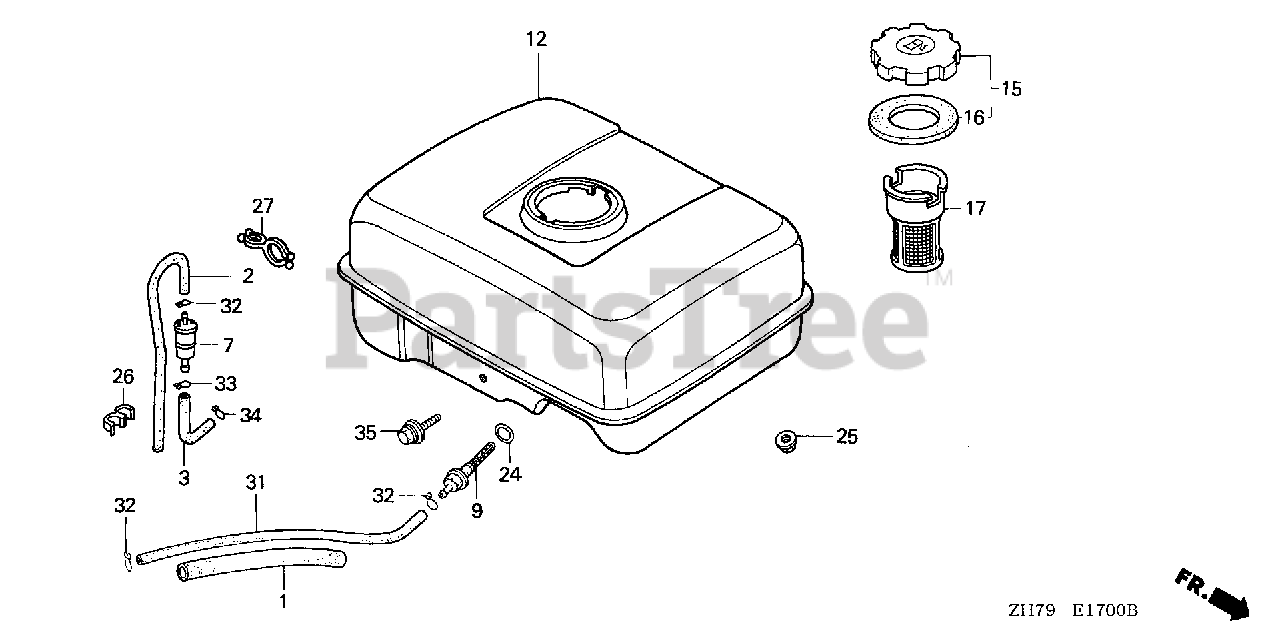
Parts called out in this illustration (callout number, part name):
1	RUBBER, SUPPORTER (107MM)
9	JOINT, FUEL TANK
12	TANK, FUEL *NH31* (MCKINLEY WHITE)
15	CAP, FUEL FILLER
16	GASKET, FUEL FILLER CAP
24	O-RING (13.5X1.5) (ARAI)
25	NUT, FLANGE (6MM)
31	BULK HOSE, FUEL (4.5X3000) (4.5X140)
32	CLIP, TUBE (B8)
35	BOLT, FLANGE (6X29)
